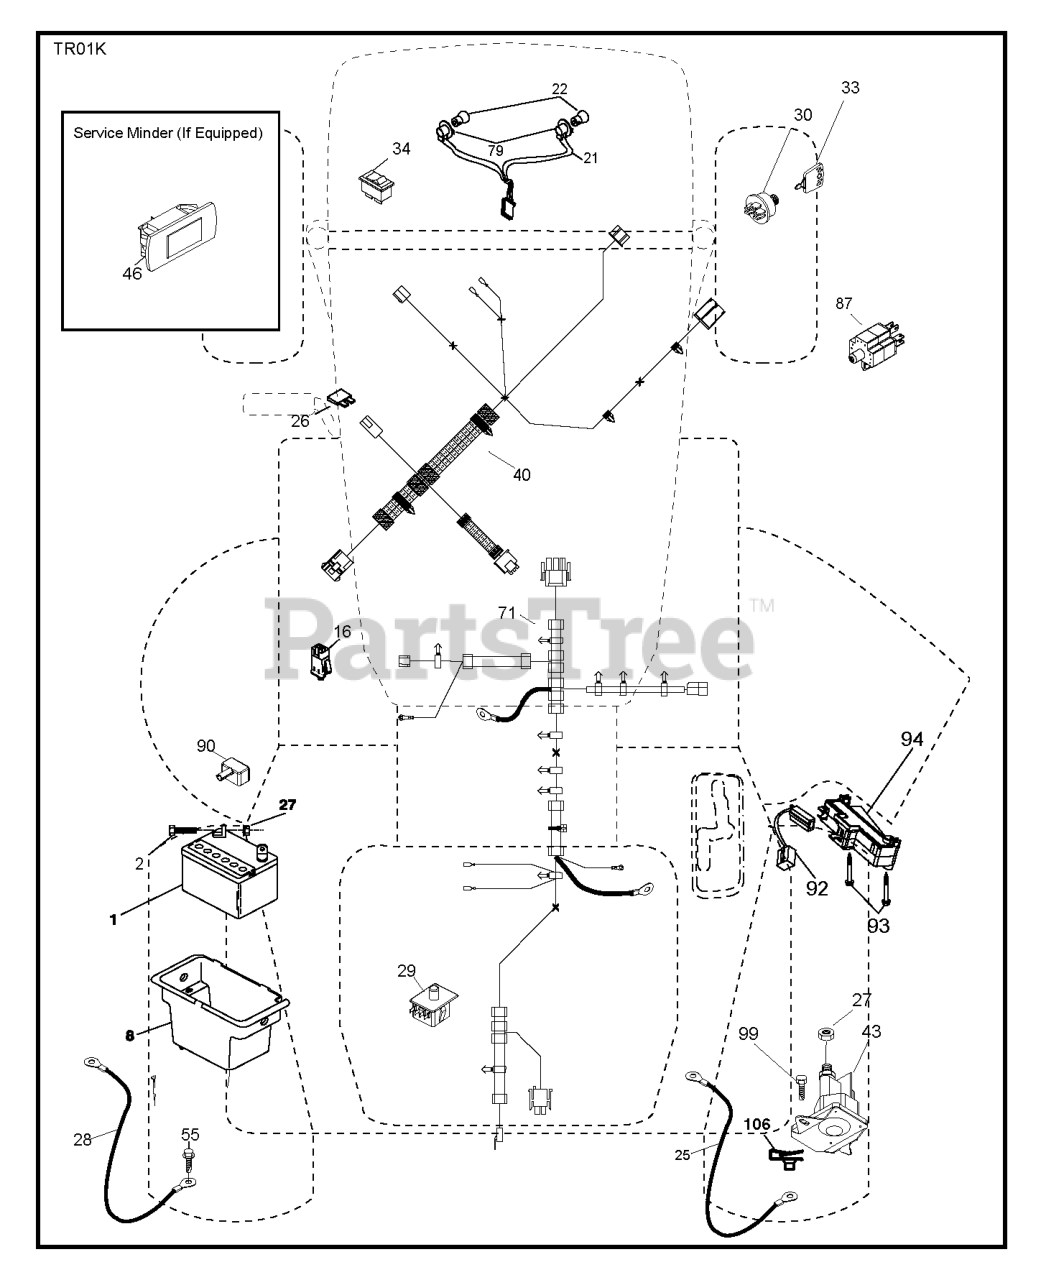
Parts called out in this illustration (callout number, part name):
1	REPL BY 532 12 38-99
2	DRAWBAR.STGT
2	BOLT.HEX.1/4.X.3/4.DICHROMATE
3	APPLIQUE.SUBASM.GT.HUSQ.II
5	DASH.UPPER.ASM.GT2.DR.EL.EFM
8	BOX.BATTERY.MNT.REAR.L
14	HOOD.ASM.HUSQVARNA.GT.TEX.ORAN
15	LED LIGHT.LH
16	SWITCH INTERLOOK PUSH-IN
21	HARNESS.LIGHT W/4152J BULBS
25	LENS.RH
25	CABLE.BATT.RED.8GA.17
26	FUSE 20AMP
27	NUT
28	CABLE.GROUND.REAR.BATTERY.8G
29	SWITCH.SEAT.DELTA.OPC.
30	SWITCH.IGN.DELTA.W.LGH.ROS
33	KEY.CHAIN.BLISTER.PACK.GEN.INT
36	SCREW 5/16"
37	FENDER.PNT.TX.GT.CH/FW/DL.HUSQ
40	HARNESS.TEX.DASH.MAN.REAR BATT
43	SOLENOID.W/BRASS.PLUNGER
55	SCREW 5/16"
58	BRKT.SUPPORT.FNDR/TANK
71	HARNESS.TEX.CHSSIS.REAR.BATT
79	BULB HOLDER ASM.
87	SWITCH.INTRLCK.CLUTCH.
90	COVER.TERMINAL.BATTERY
92	HARNESS.PIGTAIL.CONSLE
93	SCREW.PLASTITE
94	MODULE.REVERSE.ROS
99	SCREW HEXWSHR 1/4-20X3/4
106	1/4-20 U NUT
125	CLIP.FUEL.LINE
137	BUMPER DASH
146	BOLT.RDHD.SHT.SQNK.3/8-16X5/8
150	AIR.DUCT.GTV.BLACK
151	BRACKET.PIVOT.HOOD.GT.HUSQ.II
152	SHIELD.BROWNING.PNT.GT.V2
159	SCREW, 3/8-16X3/4
161	CONSOLE.WINDOW.FUEL.HUSQ.GT
165	SUPPORT.TANK.REAR.B/TE
175	PLATE.PNT.CROSSMEMBER.HUSQ/PRE
176	SCREW.#10-24X5/8.RN.QU
177	BUSHING STEERING
180	CHASSIS LTGT BOLTED PAINTED X4
182	DASH.LOWER.COMMON.12V.ADAPTOR
189	SCREW
191	INSERT INFLECT.RH
196	CONSOLE.ASM.DECKLIFT.HUSQGT.DL
199	PLATE.DECK.LIFT.HUSQVARNA.GT
202	VENT.SIDE.RH.GT.HUSQ.II.
203	VENT.SIDE.LH.GT.HUSQ.II.498
204	VENT.TOP.ASM.HUSQ.GT2
205	SIDE.TRIM.RH.GT.HUSQ.II
206	SIDE.TRIM.LH.GT.HUSQ.II.GRAY
207	BEZEL GT2 LED RH W/ LOWER.ATT
208	BEZEL GT2 LED LH W/ LOWER ATT
214	CLIP.RETAINER.TINNER.
217	ROD.PIVOT.HOOD
221	REFLECTOR.LH.TEX GT HU
228	STUD.W/"D"ANTI-ROTATION
236	NUT.CENTERLOCK.5/16-
281	SCREW 3/8-16X1
296	LED LIGHT.LH
297	INSERT REFECT LH
299	LED LIGHT.RH
306	NUT LOCK FLG 3/8-16 UNC
335	COVER.LOWER.DASH.RH.BLACK
336	COVER-LH.LOWER.DASH.GT2.BLACK
350	CLIP.X-MAS.TREE
375	BUMPER CLIP-ON. DASH 1"
378	BUSHING FLANGE; PLASTIC
379	CHASSIS.PLATE.REINFORCEMNT.431
